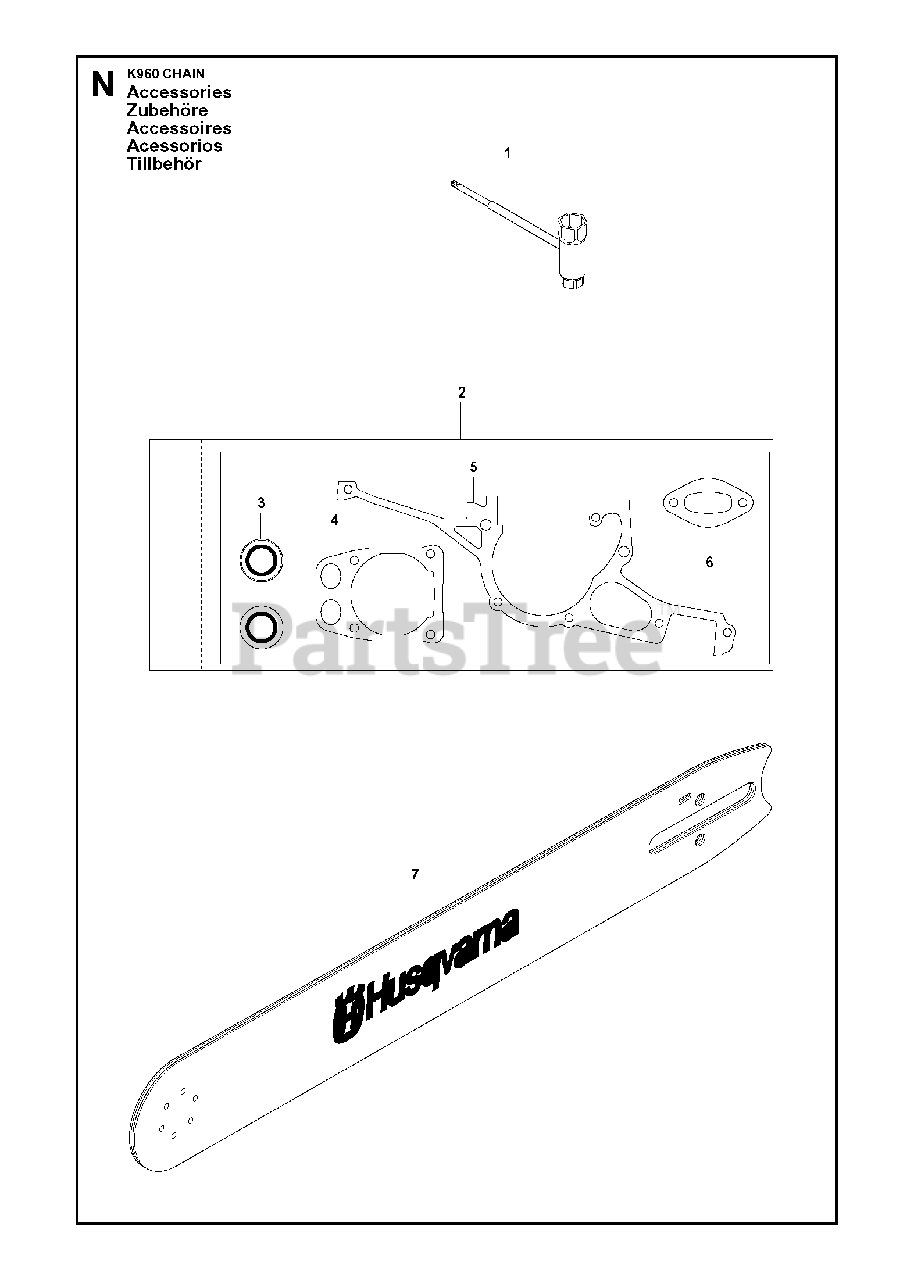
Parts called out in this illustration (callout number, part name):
2	GASKET KITIncl. 3 - 6
3	SEALING RING
4	GASKET
5	GASKET
6	GASKET
